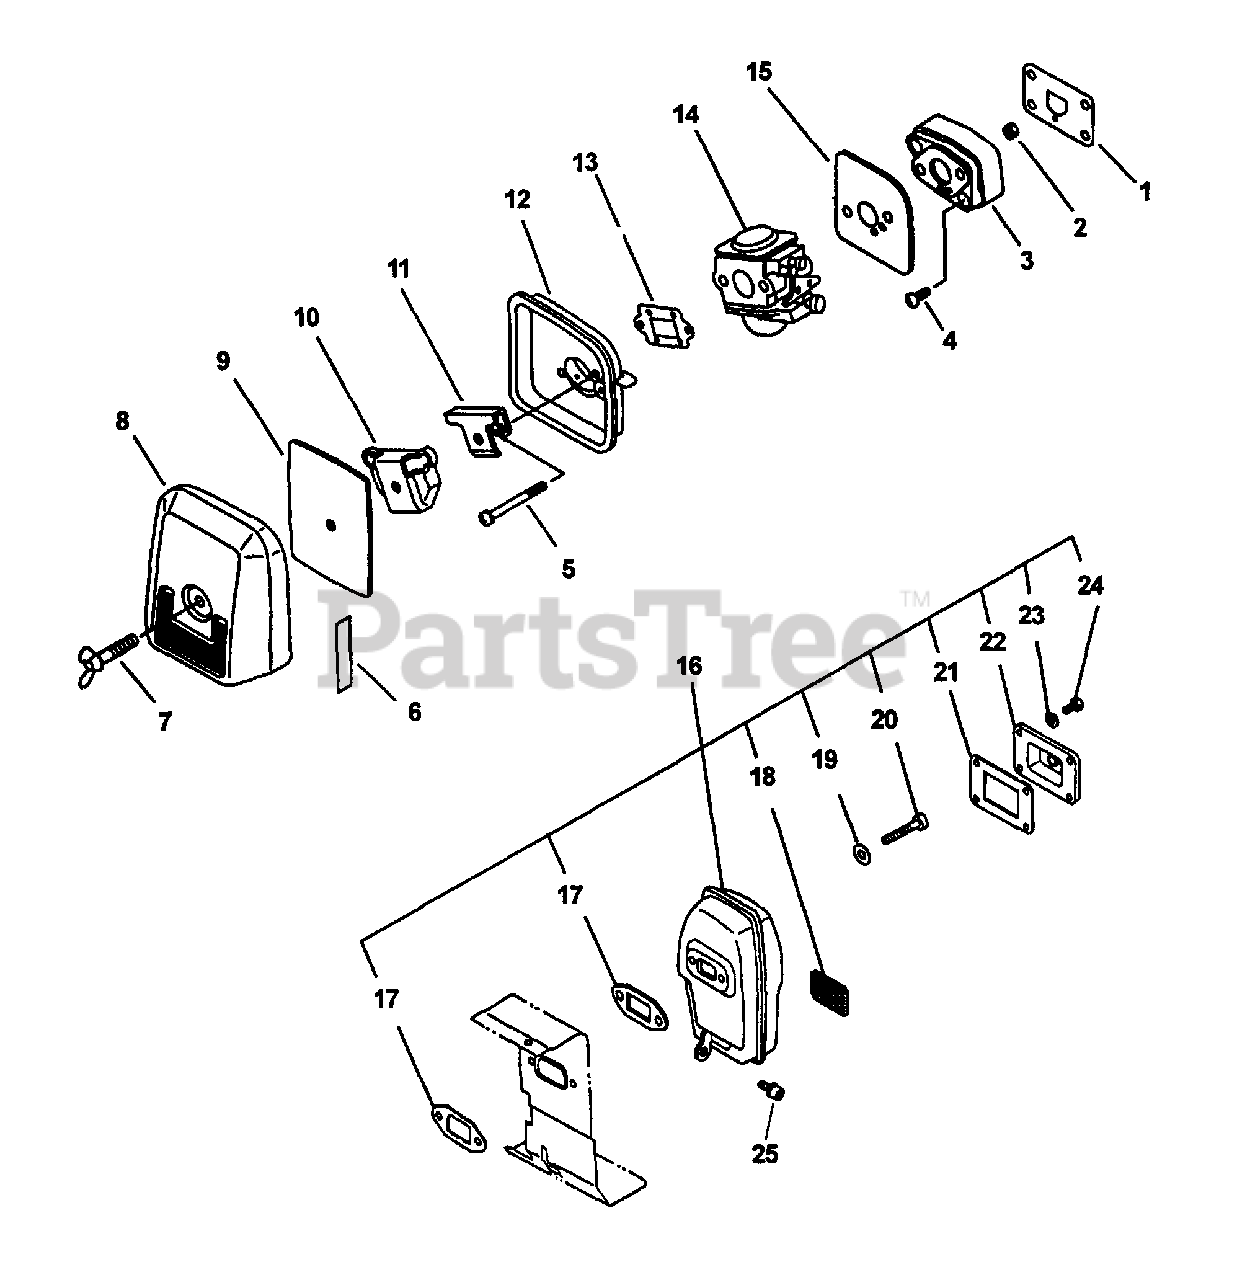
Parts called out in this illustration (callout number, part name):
1	GASKET, INTAKE
2	NUT M5
3	INSULATOR, INTAKE
4	SCREW 5×22
5	SCREW 5×55
6	LABEL, CHOKE
7	THUMBSCREW
8	COVER, AIR FILTER
9	FILTER, HEAVY-DUTY AIR
11	PLATE, PREVENT
12	AIR FILTER CASE ASSY
14	CARBURETOR - WT-417
15	GASKET, INTAKE
16	MUFFLER ASSY
17	GASKET, EXHAUST
18	SCREEN, SPARK ARRESTER
19	WASHER, FLAT 5.5×10×0.8
20	BOLT 5×60
21	GASKET, EXHAUST
22	GUIDE, EXHAUST
23	WASHER, SPRING 4 MM
24	SCREW - 4×12
25	BOLT 5×16
